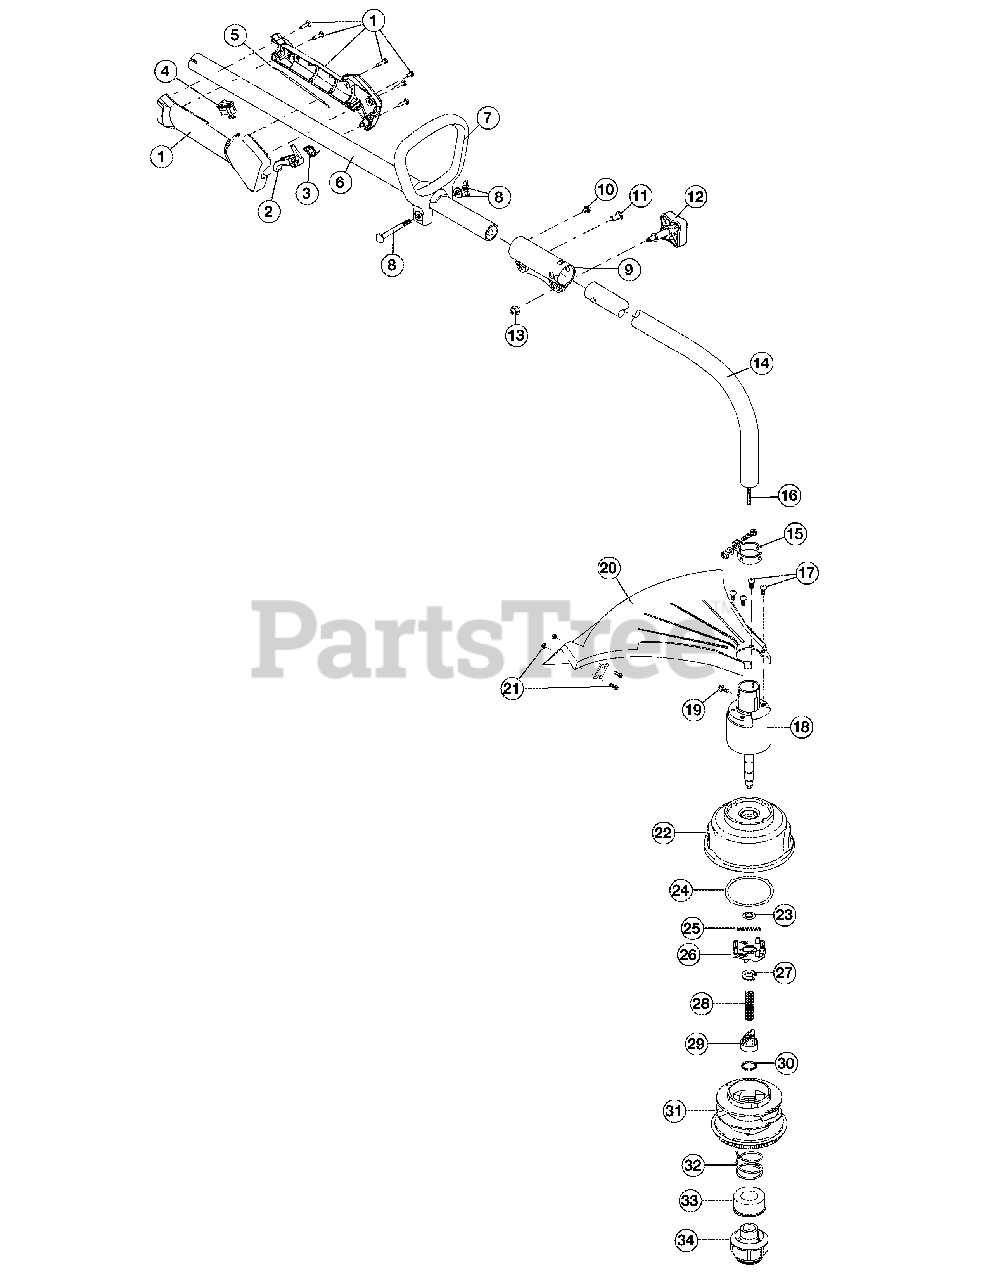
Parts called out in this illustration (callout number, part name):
1	Throttle Housing Assembly
2	Throttle Trigger
3	Throttle Trigger Spring
5	Throttle Cable
6	Upper Drive Shaft Housing Assembly
7	D-Handle
8	D-Handle Hardware
9	Split Boom Coupler
12	Adjustment Knob
13	Knob Retaining Nut
14	Lower Drive Shaft Housing Assembly
15	Lower Clamp Assembly
16	Lower Flexible Drive Shaft
17	Shield Mount Screw
18	Bushing Housing Assembly
19	Anti-Rotation Screw
20	Shield Assembly
21	Blade Assembly
22	Outer Spool Assembly
24	Thrust Washer
31	Inner Reel
34	Bump Head Knob Assembly
